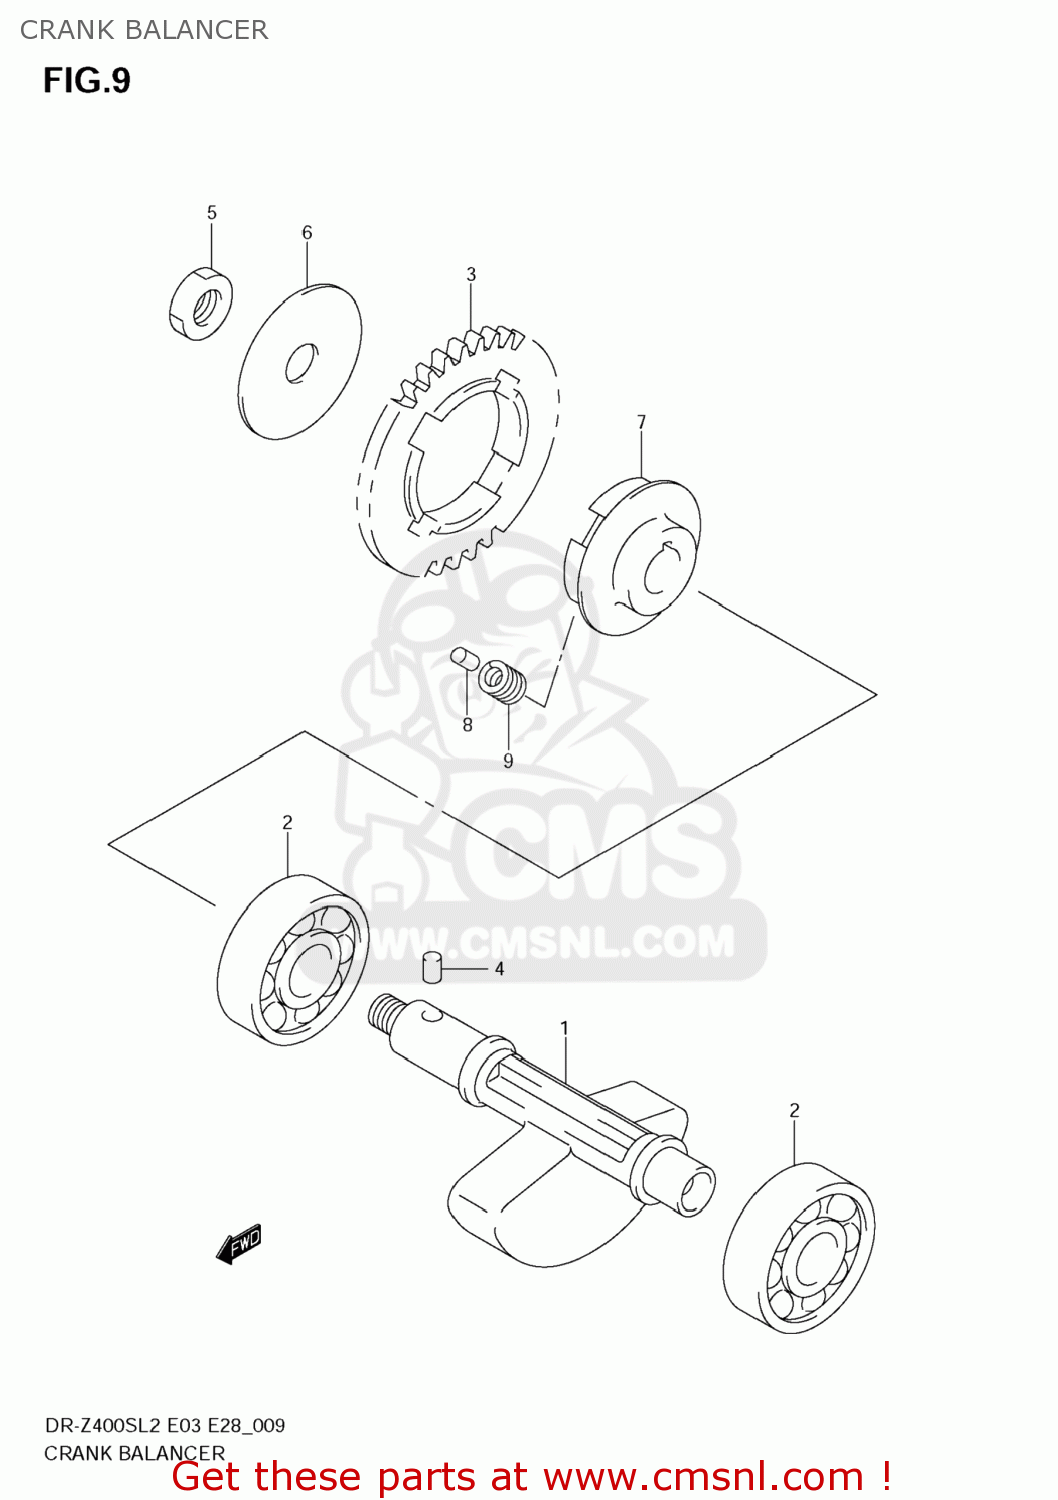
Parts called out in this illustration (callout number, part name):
1	BALANCER,CRANK
2	BEARING(15X42X13)
3	GEAR,CRANK BALANCER DRIVEN
4	PIN(5X8)
5	NUT
6	SHIM(12.2X47X1.6)
7	RACE,CRK BAL DRIVEN
8	PIN(4.5X9.5)
9	SPRING
